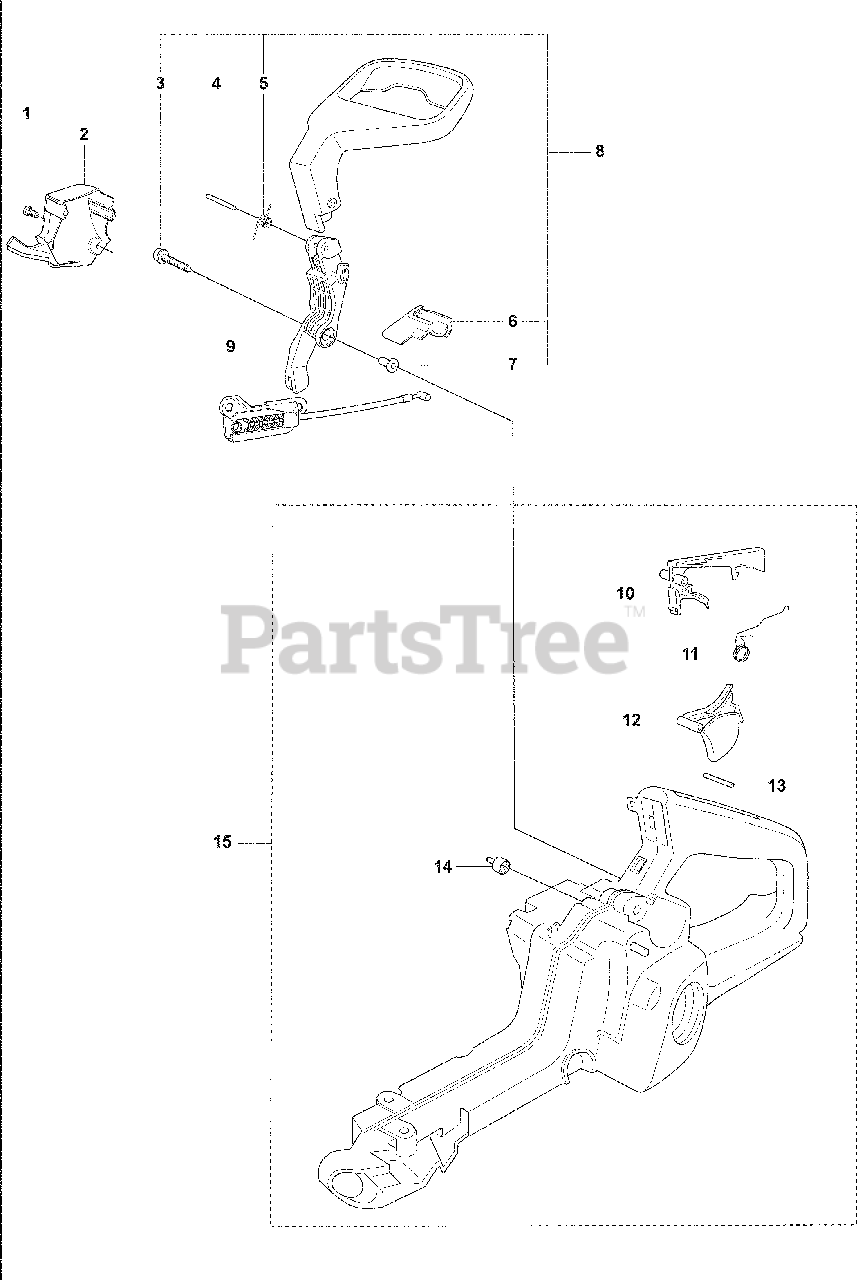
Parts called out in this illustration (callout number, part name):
4	Grooved Pin
9	WIRE ASSY
10	Throttle Lock
14	Tank Vent Assembly
